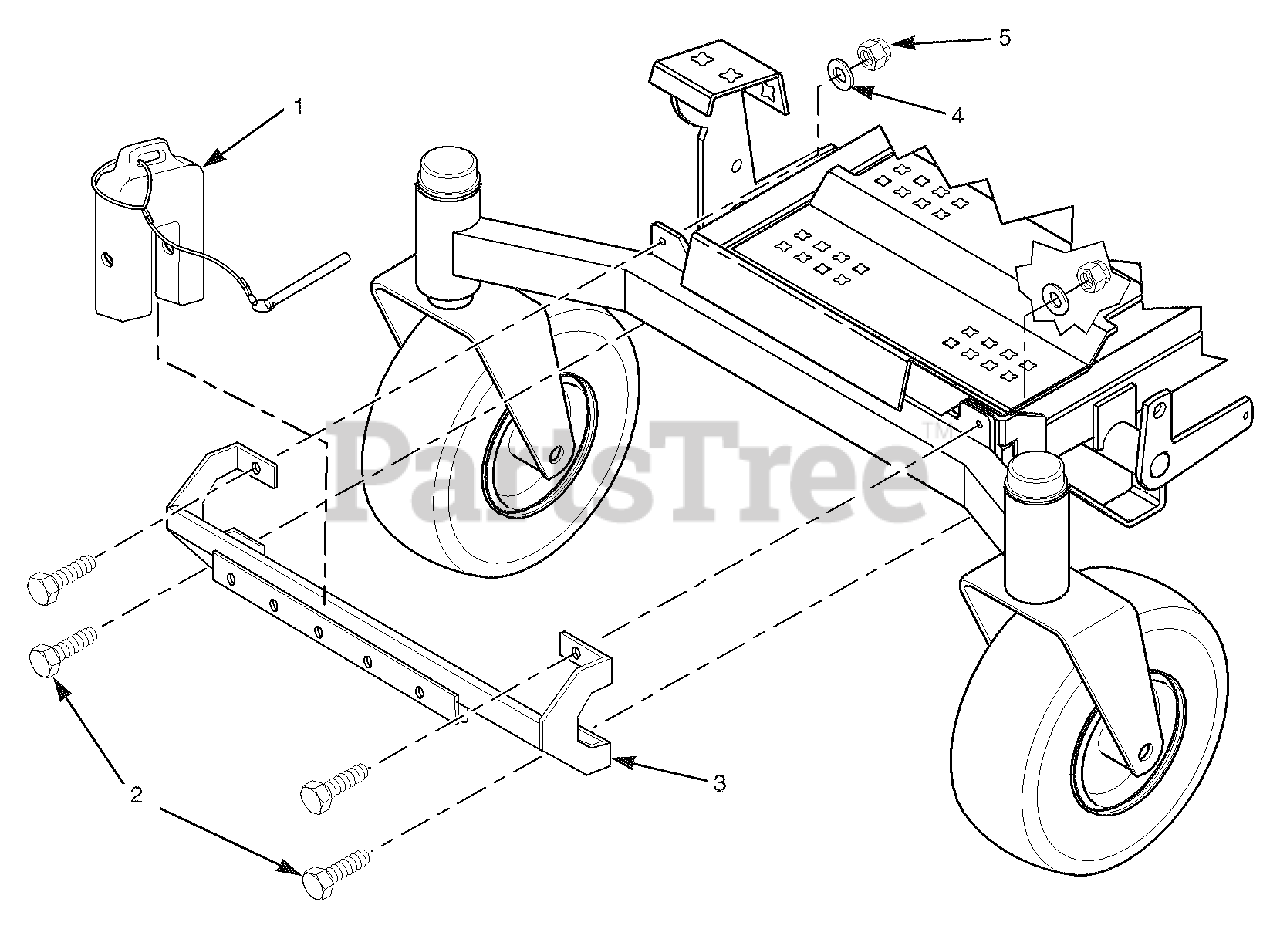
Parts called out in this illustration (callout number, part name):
1	Weight Assembly
2	Bolt, Hex Head 7/16-14 x 1-3/4"
3	Suppor t Weldment, Weights
4	Flatwasher, 7/16-.500 x 1-1/4"
5	Nut, Elastic Stop 7/16-14
